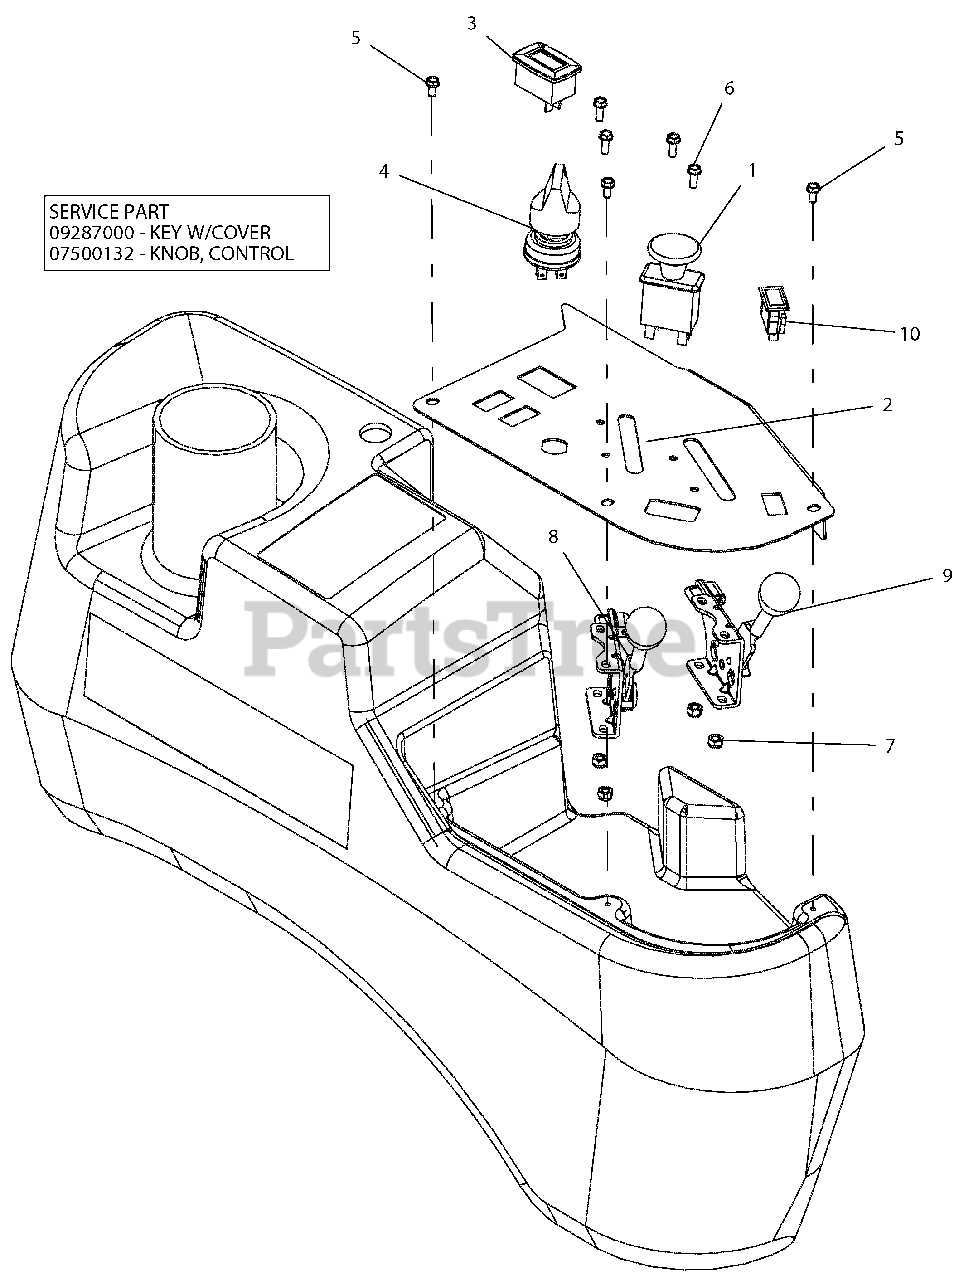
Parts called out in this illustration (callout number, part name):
1	SWITCH, CLUTCH
2	PANEL, CONTROL-BLACK
3	METER, HOUR W/MAINTENANCE
4	SWITCH, IGNITION
5	SCR-MCH 10-24X.38 HWHSTAINLESS
6	@SCR-MCH 10-24X.50 HWH YWZC
7	NUT-LK-NYL #10-24 YWZC
8	CABLE, PRO-CONTROL THROTTLE
9	CABLE, THROTTLE 53"
10	LIGHT, INDICATOR
